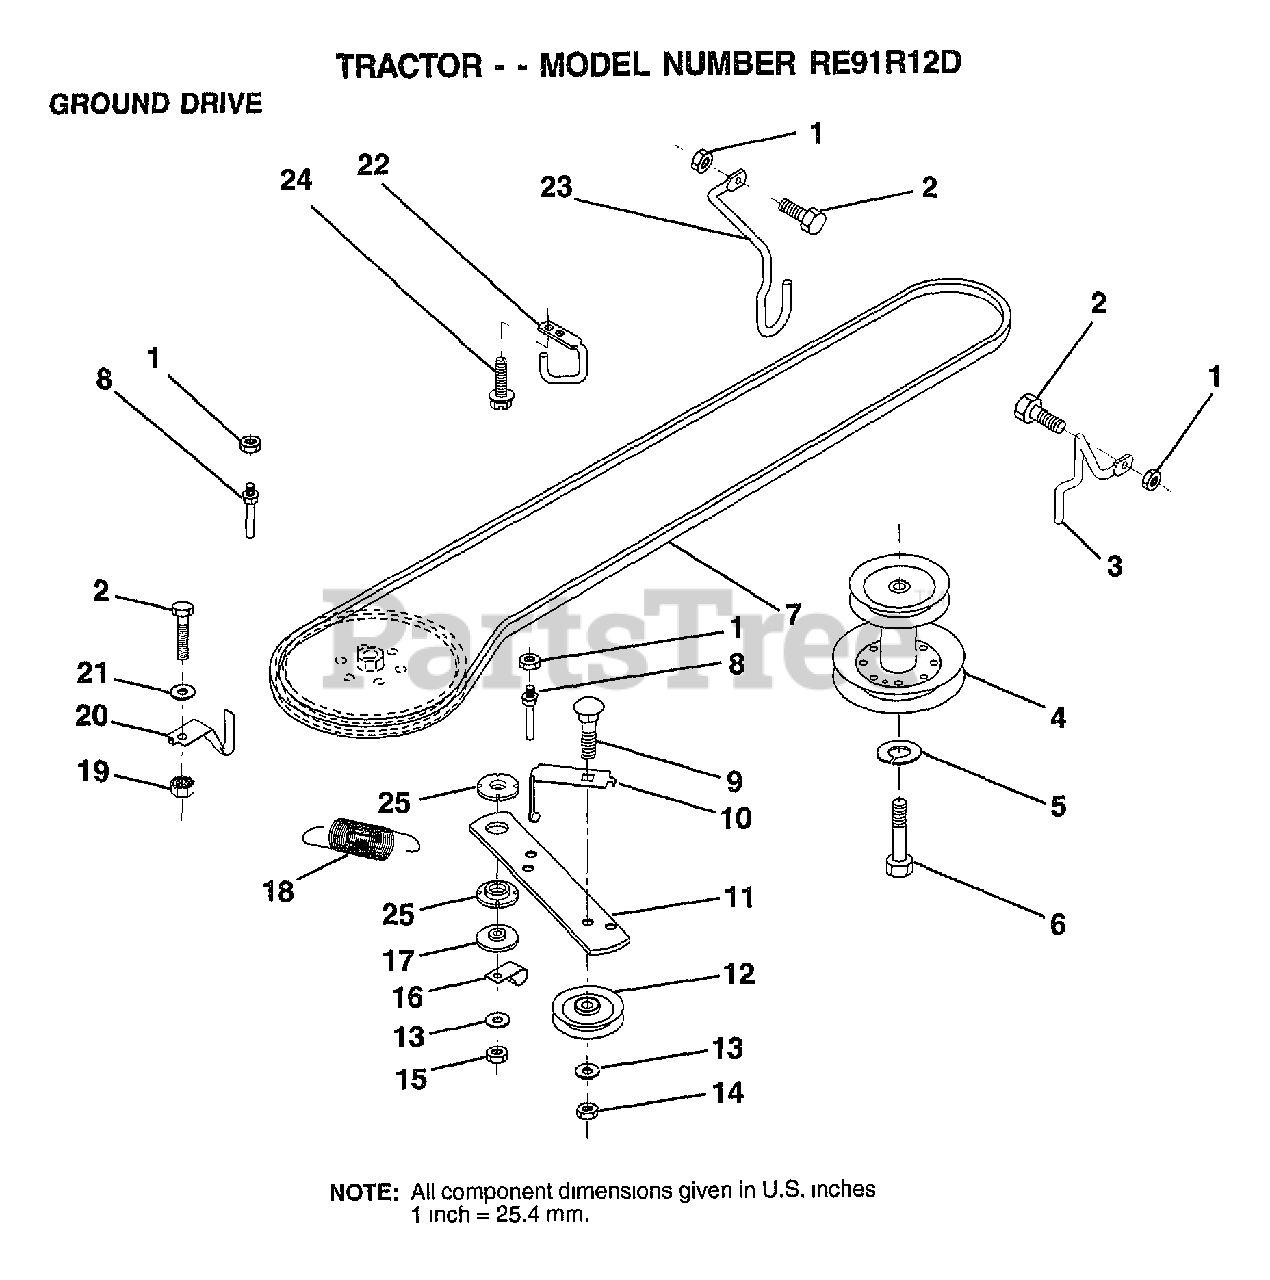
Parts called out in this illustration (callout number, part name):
2	BOLT
3	KEEPER RH
4	PULLEY.ENGINE.LR
5	LOCKWASHER
6	HEX BOLT
7	V BELT
8	"KEEPER,DRIVE BELT"
9	BOLT
10	"KEEP,IDLER DR BEL"
11	ARM-IDLER.DR.GRND
12	PULLEY.IDLER.FLAT
13	WASHER
14	LOCKNUT
16	"CLIP,INSULATOR"
17	SPACER
20	KEEPER.BELT.T/A
21	WASHER
22	"KEEPER,FRA DR BEL"
23	KEEPER MOWER LH
24	SCREW
25	BUSHING.NYLON
